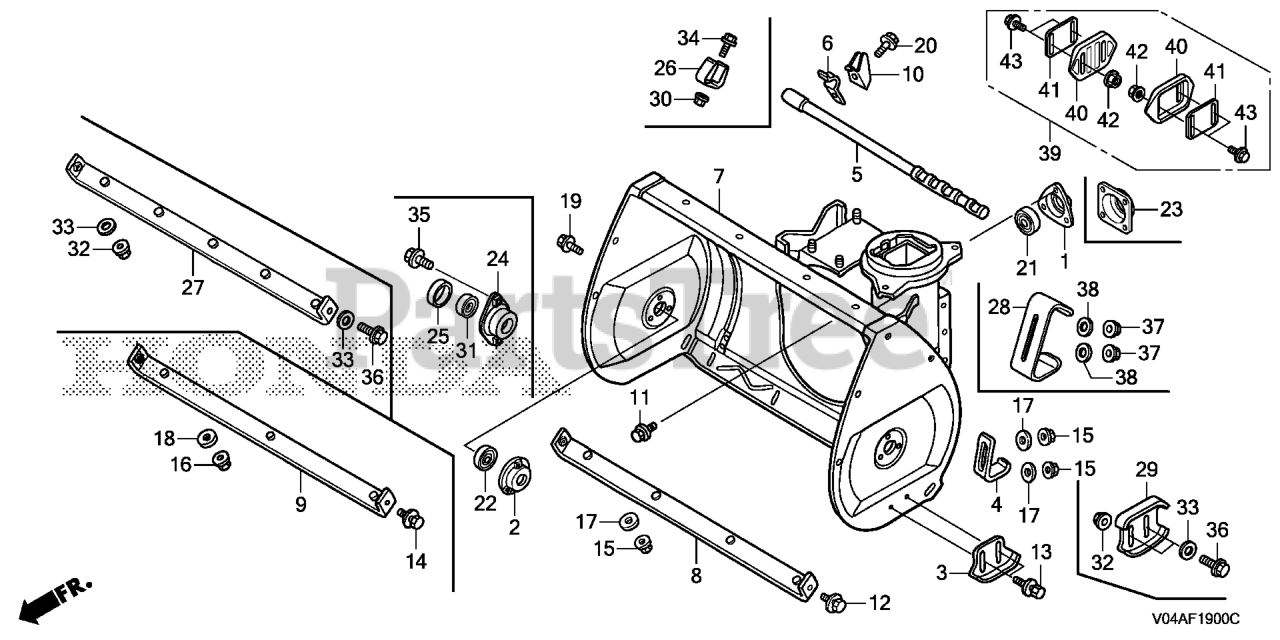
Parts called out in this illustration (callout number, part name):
5	BAR, SNOW DROP
7	HOUSING, AUGER *R280* (POWER RED)
11	BOLT, FLANGE (8X12)
21	BEARING, RADIAL BALL (6205UU)
23	HOLDER, BLOWER SHAFT BEARING
24	HOLDER, AUGER BEARING
25	SPACER, AUGER BEARING
26	BRACKET, SNOW DROP BAR
27	BLADE, SCRAPER
28	SKID, AUGER
29	SKID, AUGER
30	NUT, NYLON RING (6MM)
31	BEARING, RADIAL BALL (6203-19.05)
32	NUT, FLANGE (8MM)
33	WASHER, PLAIN (8MM)
34	BOLT, FLANGE (6X12) Use from Engine SN 2086984.
35	BOLT, FLANGE (8X12)
36	BOLT, FLANGE (8X16)
37	NUT, FLANGE (8MM)
38	WASHER, PLAIN (8MM)
39	RESIN SKID SHOE(KIT)
40	SKID, AUGER
41	PLATE, AUGER SKID
42	NUT, FLANGE (8MM)
43	BOLT, FLANGE (8X22)
